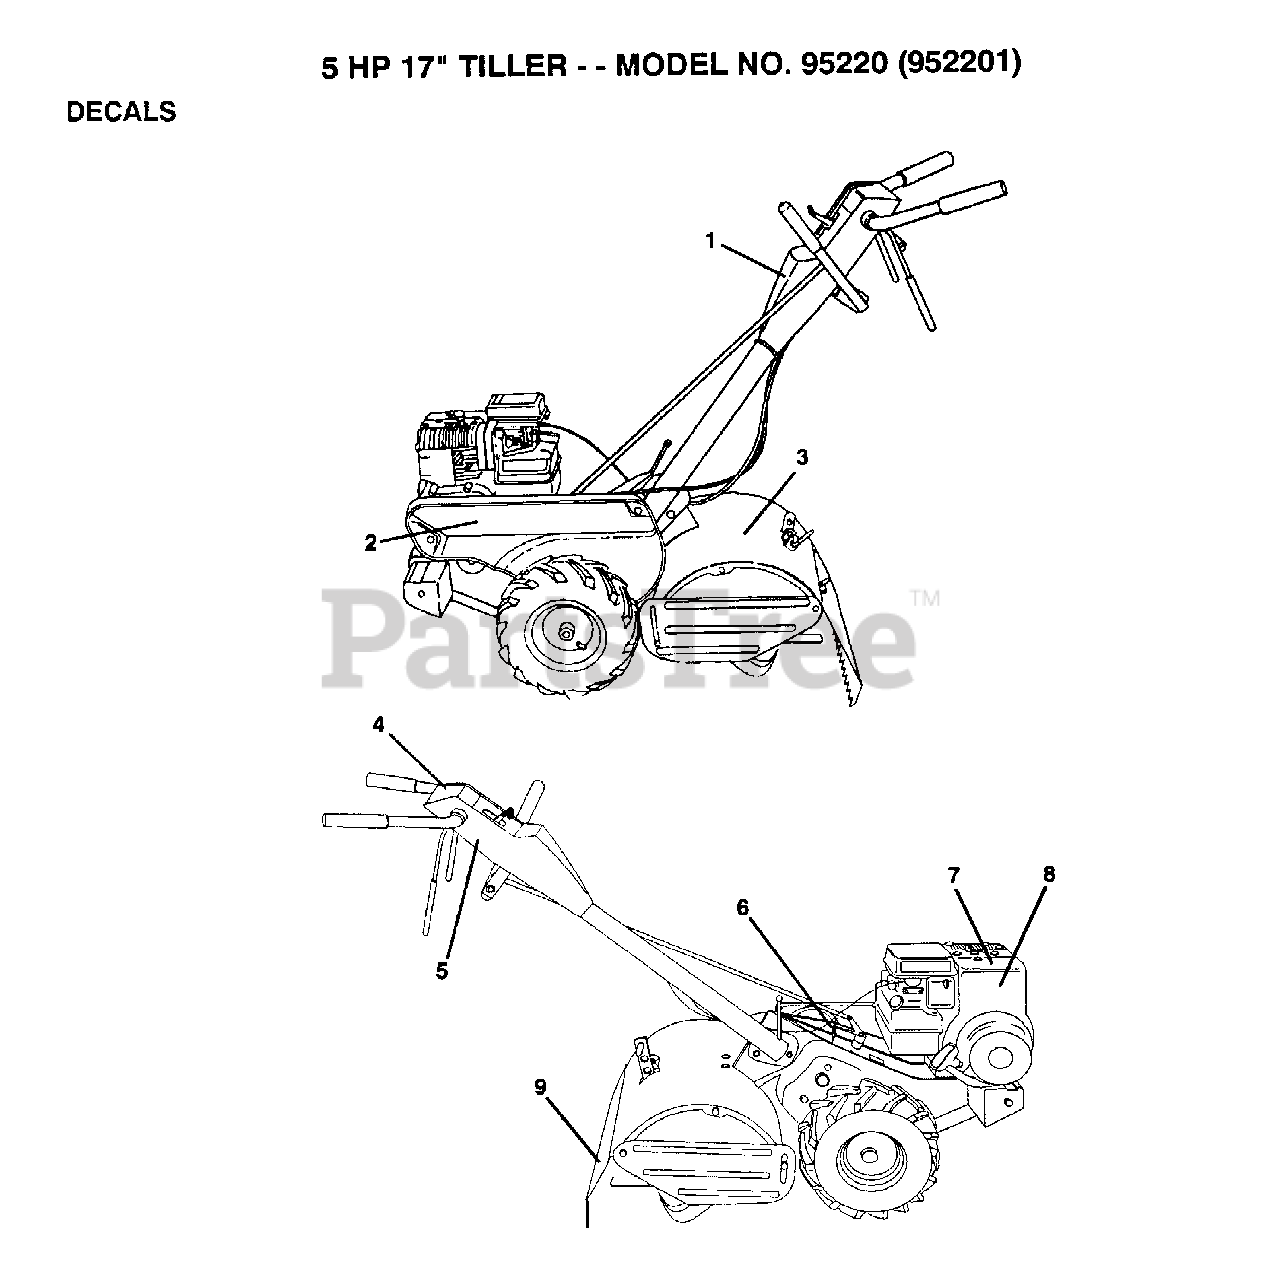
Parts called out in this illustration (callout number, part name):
1	DECAL.PANEL.CONTR
2	DECAL.GUARD.BELT
4	DECAL.INSTRUCTION
5	DECAL TI
6	DECAL CRT
9	DECAL TI
